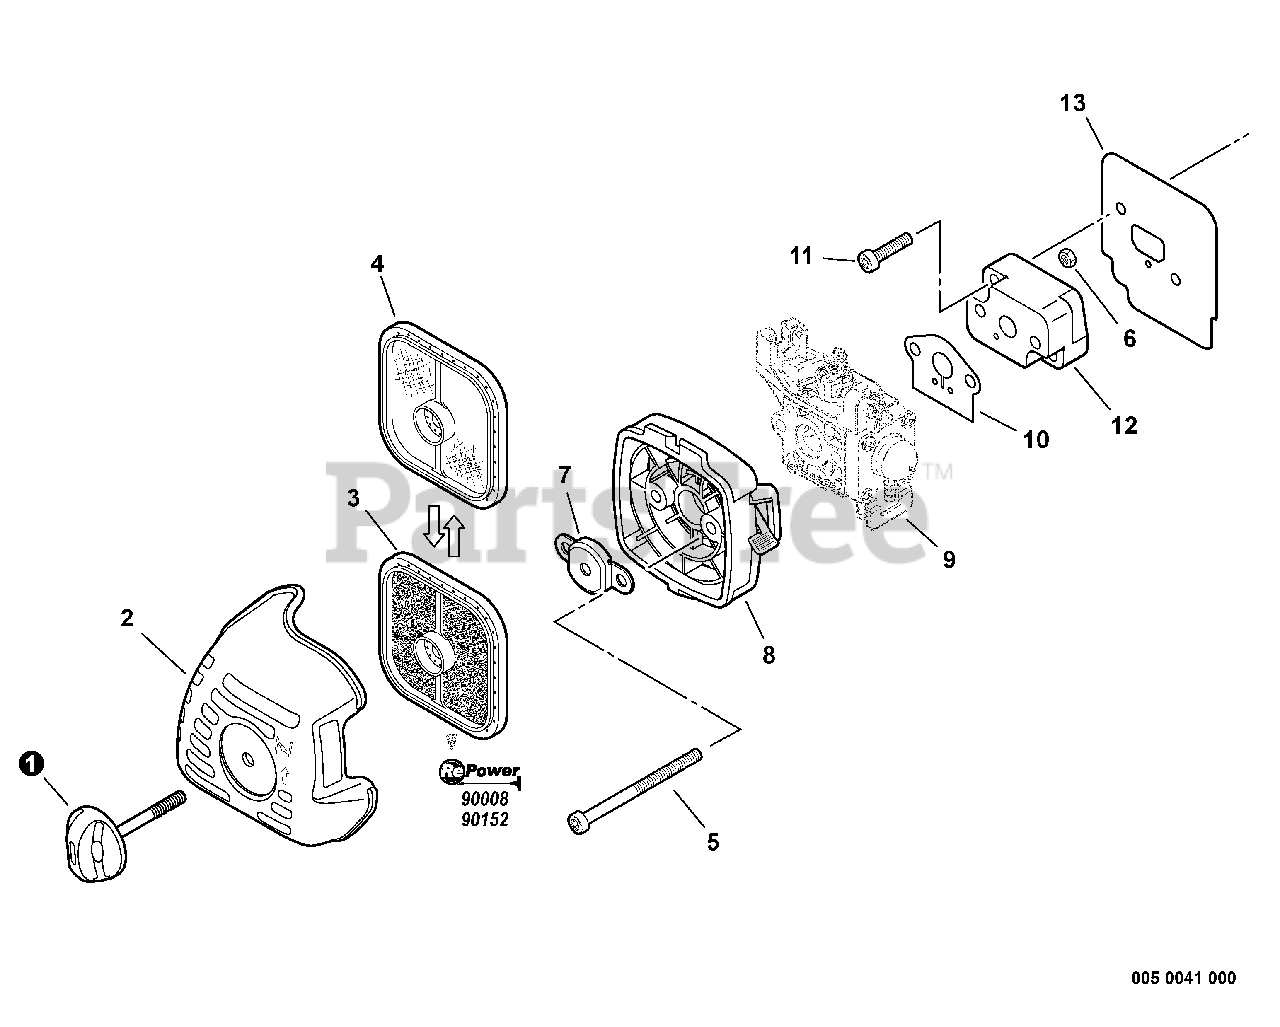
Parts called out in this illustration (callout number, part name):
1	THUMBSCREW
2	COVER, AIR FILTER
3	FILTER, AIR - DOUBLE LAYER
4	FILTER, AIR - SINGLE LAYER
5	BOLT, TORX 5×65
6	NUT M5
7	PLATE, PREVENT
8	CASE ASSY, AIR FILTER
9	CARBURETOR
10	GASKET, INTAKE
11	BOLT, TORX 5×20
12	INSULATOR, INTAKE
13	HEAT SHIELD, INTAKE
14	TUNE-UP KIT - REPOWER
15	FILTER KIT - REPOWER
